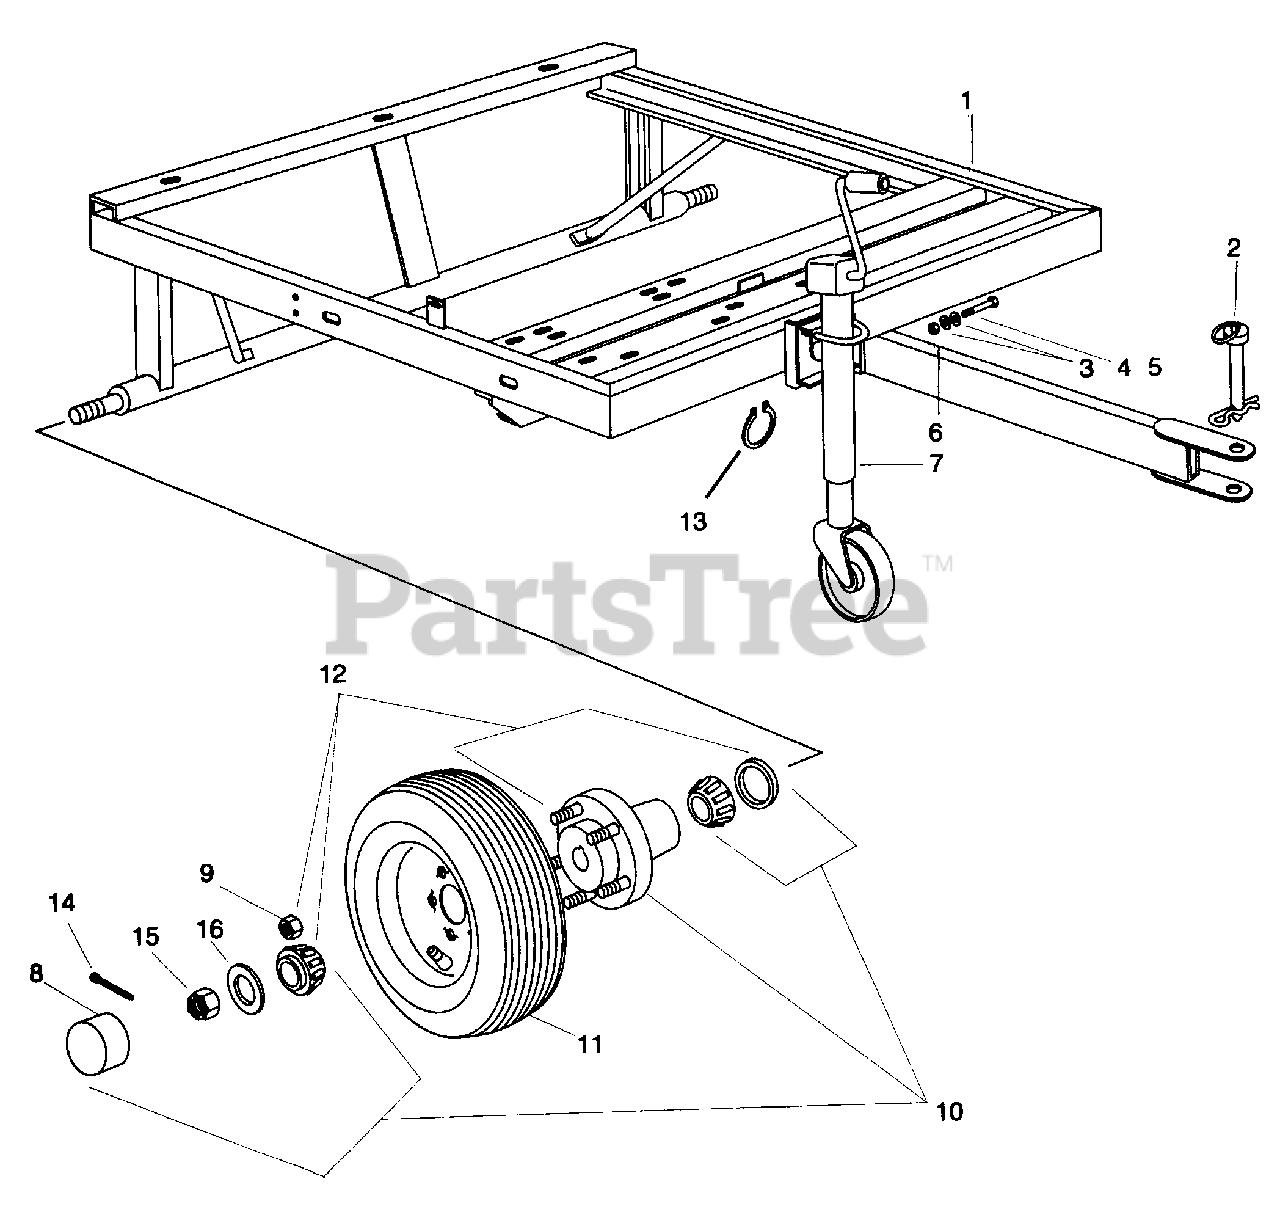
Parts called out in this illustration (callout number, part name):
1	Frame Weldment
2	Hitch Pin 1 Inch
3	Wshr-Fl-Stl .688 x 1.75 x .134
4	Blt-Hex .62 - 11 x 3.00 Pl Gr 5
5	Tongue Weldment
6	Nut-Lk-Ctr .62-11
8	Dust Cap
9	Kit, Wheel Nut
10	Kit, Hub Complete 1050 Vac
11	Tire & Wheel Assembly
12	Hub Assembly
13	Ring-Retaining-External 2.500 x .078
14	Pin-Cotter .12 x 1.25
15	Wheel Nut .50-20
16	Washer-Flat-Steel 2.0 x 1.12 x .148
